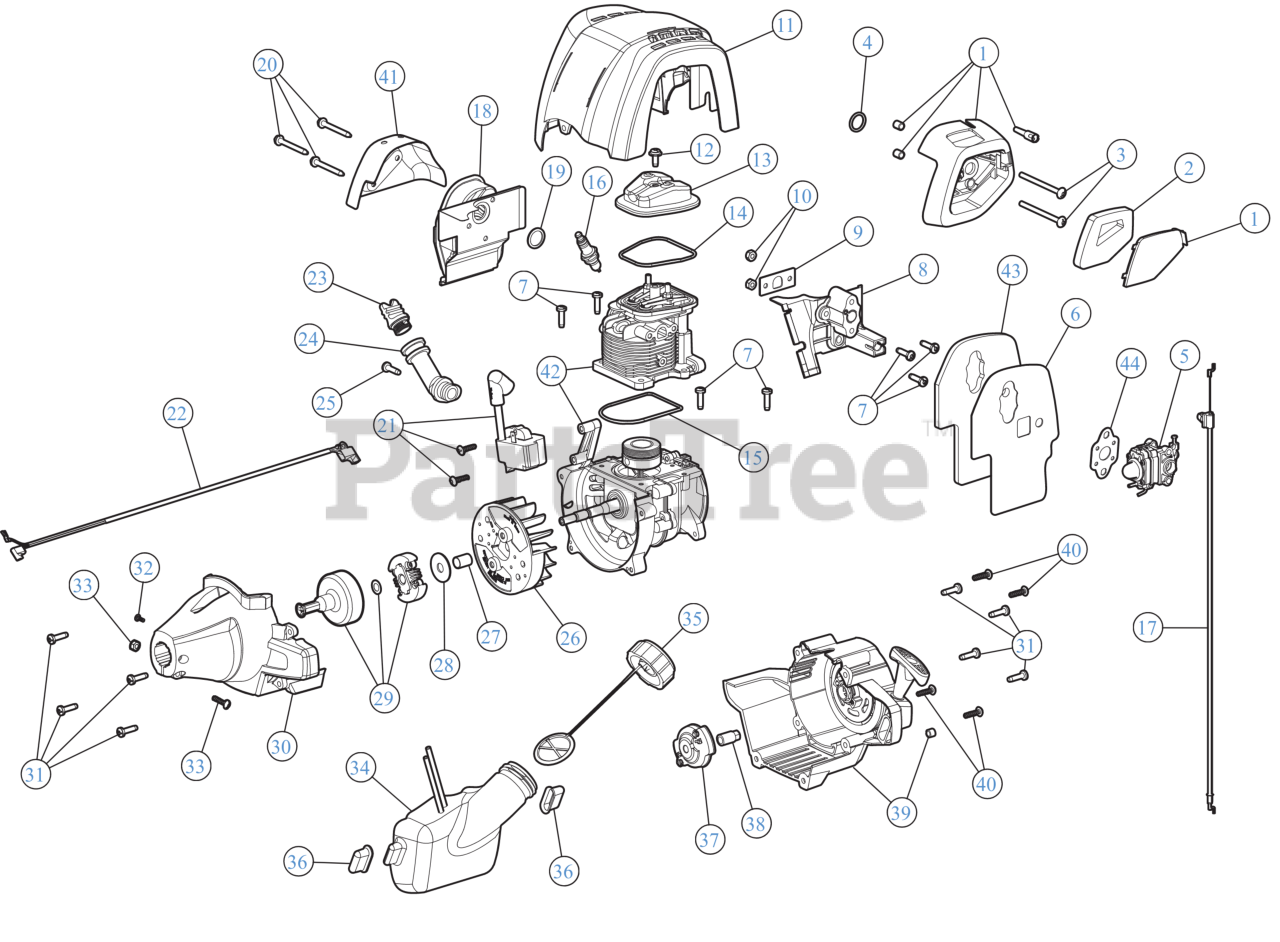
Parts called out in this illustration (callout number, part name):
1	AIR CLEANER
2	AIR FILTER
3	SCREW 10-32X3
5	CARBURETOR
6	CARBURETOR GASKET
7	SCREW, M5 x 18.7MM
9	INSULATOR GASKET
11	ENGINE COVER TOP
12	SCR, VALVE COVER
13	ROCKER COVER
15	O-RING CYL AC5
16	SPARK PLUG 4 CYCL
17	THROTTLE CABLE
18	MUFFLER ASSEMBLY AC5.1
19	GASKET/MUFFLER
20	SCREW M5 x 44MM
21	MODULE MA-95
22	WIRE LEAD AC5
24	OIL FILL TUBE
25	SCR, M5 x 15.8MM
26	FLYWHEEL W/KEY
27	SPACER .591"
28	WASH, CLUTCH O.D. 1.155 +/- .0
29	SMALL CLUTCH ASSEMBLY W/SMALL DRUM
30	CLUTCH COVER
31	SCREW M5-0.8 x 19
32	SCREW, 8-32 x .312 P
33	SCREW:CLMPNG W/NUT
34	FUEL TANK ASSEMBLY
35	FUEL CAP ASSEMBLY
36	FUEL TANK PADS
37	PAWL ASSEMBLY AC5
38	ELECTRIC START ADP
39	STARTER HOUSING ASSEMBLY
40	SCREW 8-16 x 3/4
41	MUFFLER SHLD
42	SHORT BLOCK
43	HEAT SHLD CARB AC5
44	CARBURETOR GASKET
